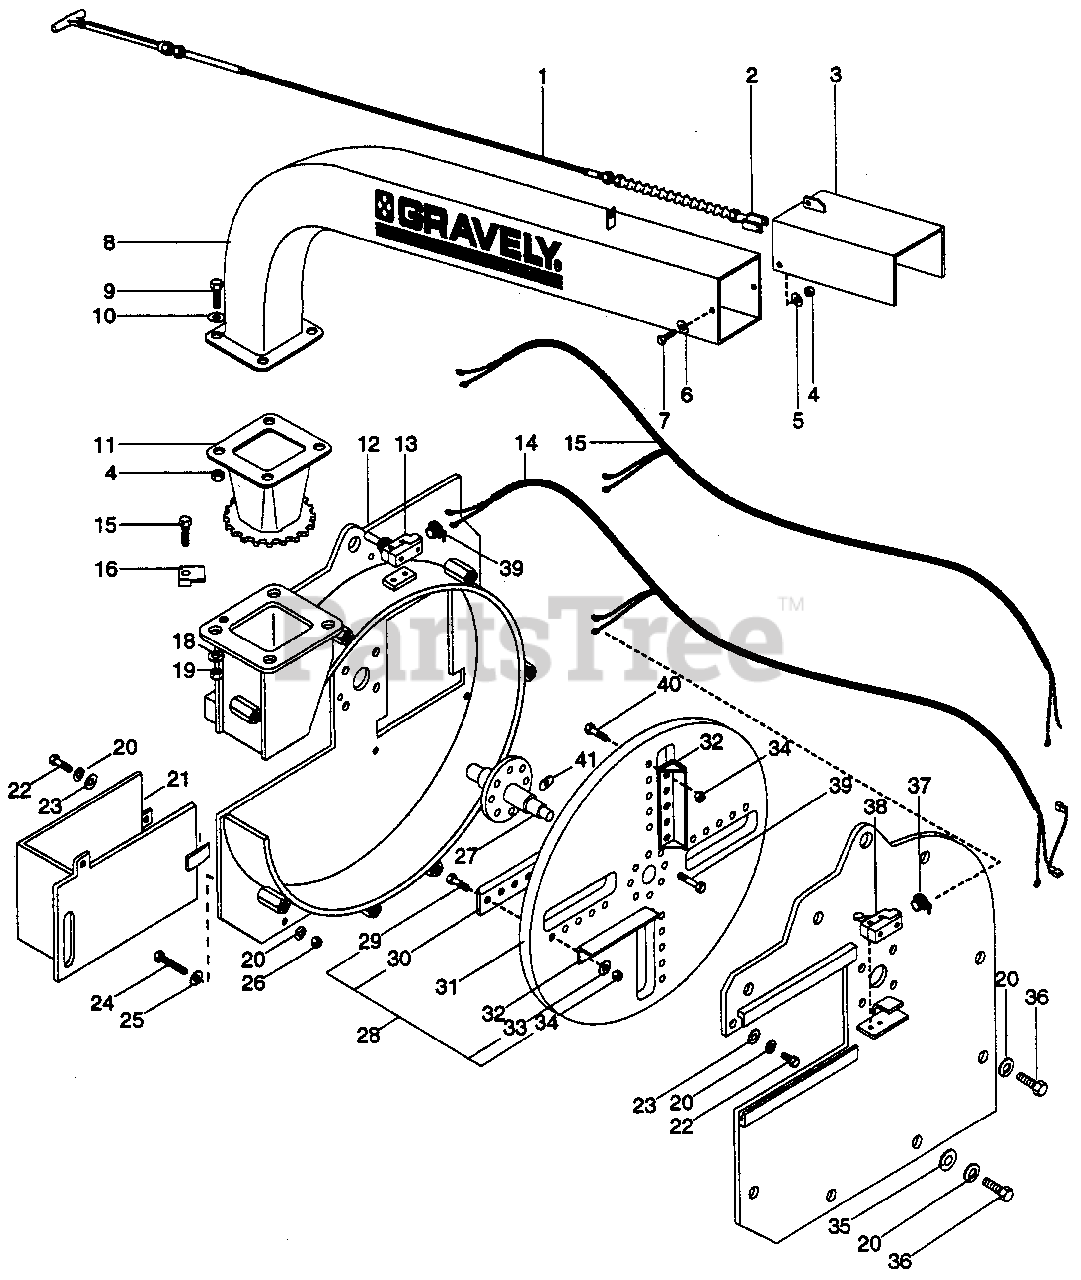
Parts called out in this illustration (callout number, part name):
1	Control Cable
2	Clevis Assembly
3	Bonnet Weldment
4	Nut Lk .375-16 Gr A Pl
5	Wshr-Fl-Ny .38 x 1.0 x .083
6	Wshr-Fl-Stl .38 x 1.60 x. 1 25 Pl
7	Blt-Hex .38-16 x 1.00 Pl Gr 5
8	Discharge Tube Weldment
9	Blt-Hex .38-16 x 1.25 Pl Gr 5
10	Wshr-Fl-Stl .406 x .812 x .065 Pl
11	Vertical Discharge Riser Weldment
12	Rear Chipper Housing Weldment
14	Safety Wire Harness
15	Safety Wire Harness
16	Blt-Hex .38-16 x 2.00 Pl Gr 5
17	Bed Knife Mount Weldment
18	Wshr-Lock .375 x.094 Med Pl
19	Nut-Hex .375-16
20	Wshr-Lock .500 x 1.51 Hvy Pl
21	Access Cover Weldment
22	Blt-Hex .50-13 x 1 Pl Gr 5
23	Wshr-Fl-Stl .531 x 1.062 x .095 Pl
24	Blt-Hex .50-13 x 2.00 Pl Gr 5
25	Wshr-Fl-Stl .563 x 1.37 x .109 Pl
26	Nut .50-13 Pl
27	Shaft Weldment
28	Chipper Knife Set
29	Blt-Hex .50-13 x 3.0 Gr 8 Fl Skh
30	Chipper Knife
31	Cutter Wheel
32	Impeller Angle Weldment
33	Wshr-Fl-Stl .568 x 1.750 x .219
34	Nut-Lk-Crown .50-13 Gr C Pl
35	Wshr-Fl-Stl .531 x 1.250 x .100 Pl
36	Blt-Hex .50-13 x 1.50 Pl Gr 5
37	Romex Connector 6623 3/8
39	Blt-Hex .62-11 x 2.25 Pl Gr 8
40	Blt-Hex .50-13 x 1.25 Pl Gr 5
41	Lock Tab
